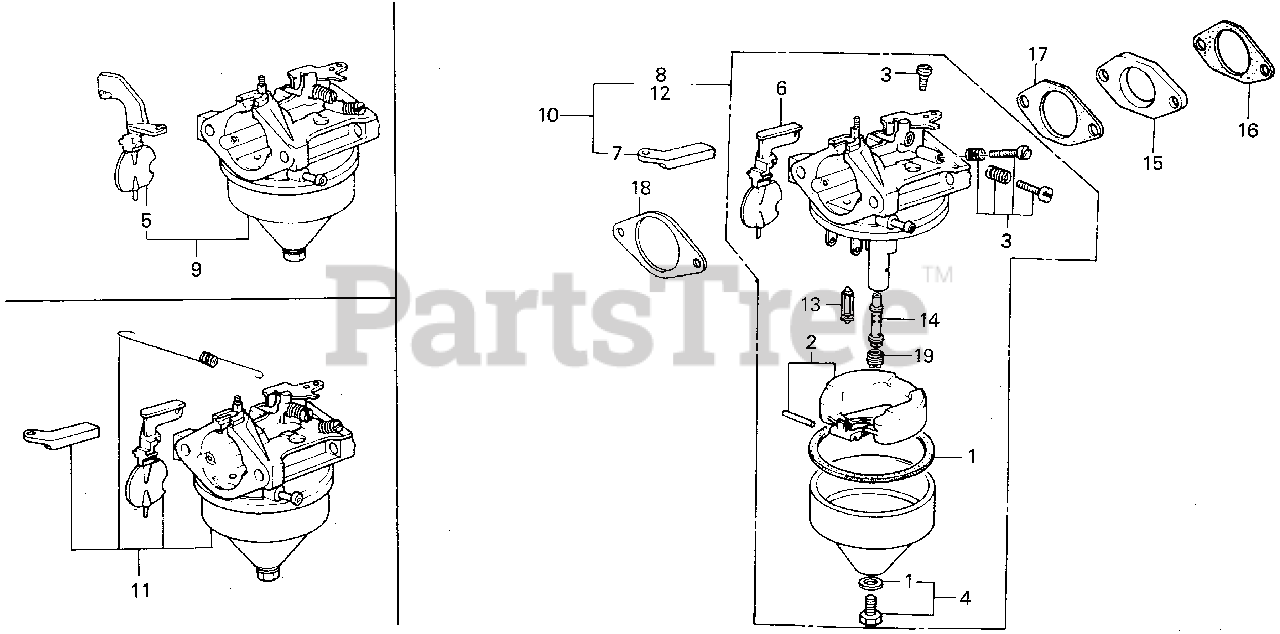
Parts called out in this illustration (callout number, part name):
1	GASKET SET
2	FLOAT SET
3	SCREW SET A
4	SCREW SET B
5	CHOKE SET (NOT AVAILABLE)
6	CHOKE SET
7	ARM, CHOKE LEVER Use from Engine SN 1139504 to 1335195.
9	CARBURETOR ASSY.
9	CARBURETOR ASSY. (BB28A A)
10	CARBURETOR ASSY.
11	CARBURETOR ASSY.
12	CARBURETOR ASSY.
12	CARBURETOR ASSY. (BB28A D)
13	VALVE, FLOAT
14	NOZZLE, MAIN
15	INSULATOR, CARBURETOR
16	GASKET, INSULATOR
17	GASKET, CARBURETOR
18	GASKET, AIR CLEANER
19	JET, MAIN (#62)
